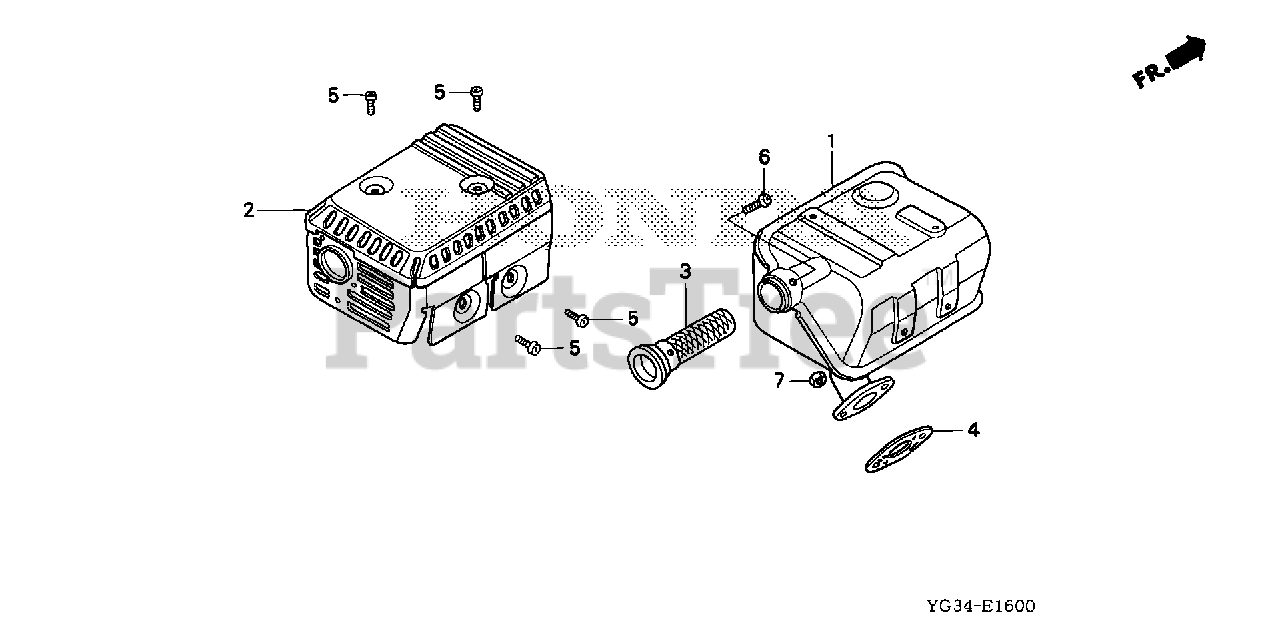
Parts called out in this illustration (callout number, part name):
1	MUFFLER
1	MUFFLER (ARRESTER)
2	PROTECTOR, MUFFLER (STD)
3	ARRESTER, SPARK
4	GASKET, MUFFLER
5	SCREW, TAPPING (5X8)
6	SCREW, TAPPING (4X6) (TO INSTALL OPTIONAL SPARK ARRESTER)
7	NUT, HEX. (8MM)
